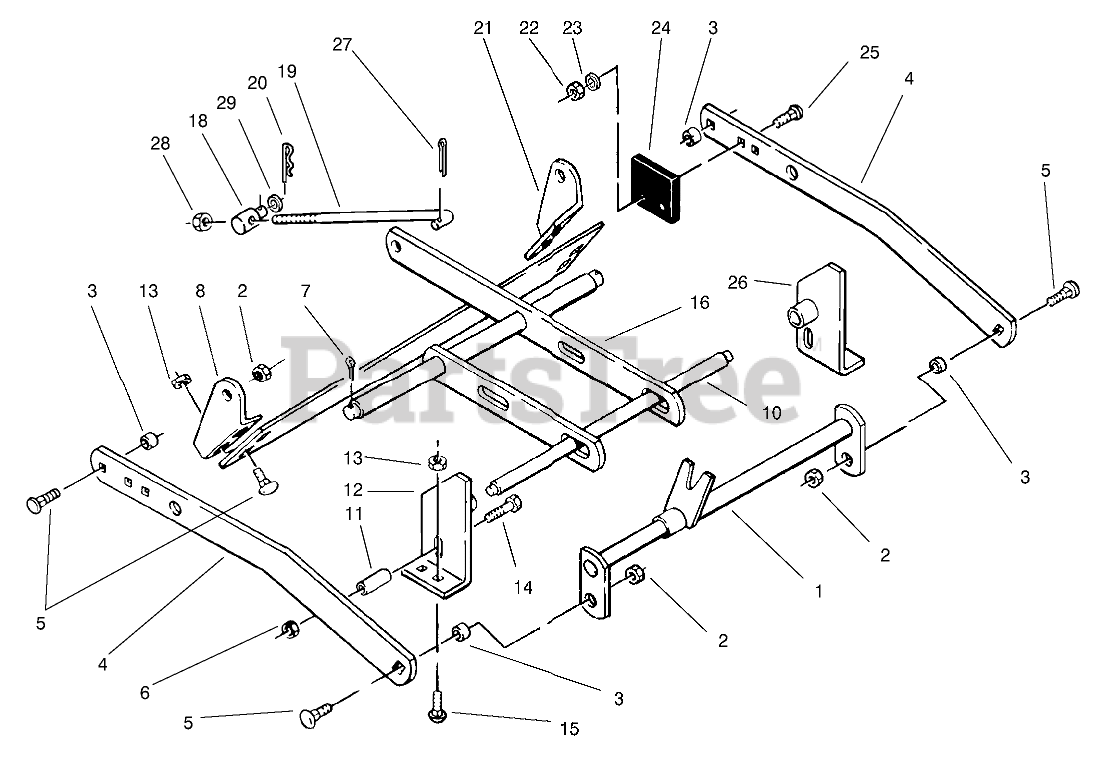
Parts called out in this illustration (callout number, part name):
1	WA HITCH (RED)
2	LOCKNUT-FLANGE
3	SPACER
4	BAR DRAFT (RED)
5	BOLT-CARR
6	NUT-LOCK, NI
7	PIN-COTTER
8	DCK BRKT R (RED)
10	SHAFT FRONT (RED)
11	SPACER
12	WA-RH FRT DK BRK (RED)
13	NUT-LOCK, NI
14	BOLT-CARR
15	BOLT-CARR
16	WA-LEVELER BAR (RED)
18	TRUNNION
19	LIFT ROD
20	PIN-HAIR
21	DCK BRKT L (RED)
22	NUT-LOCK, NI
23	WASHER-FLAT
24	BUMPER
25	SCREW-CARR
26	WA-LH FRT DK BRK (RED)
27	PIN-COTTER
28	NUT-LOCK, NI
29	WASHER-FLAT
